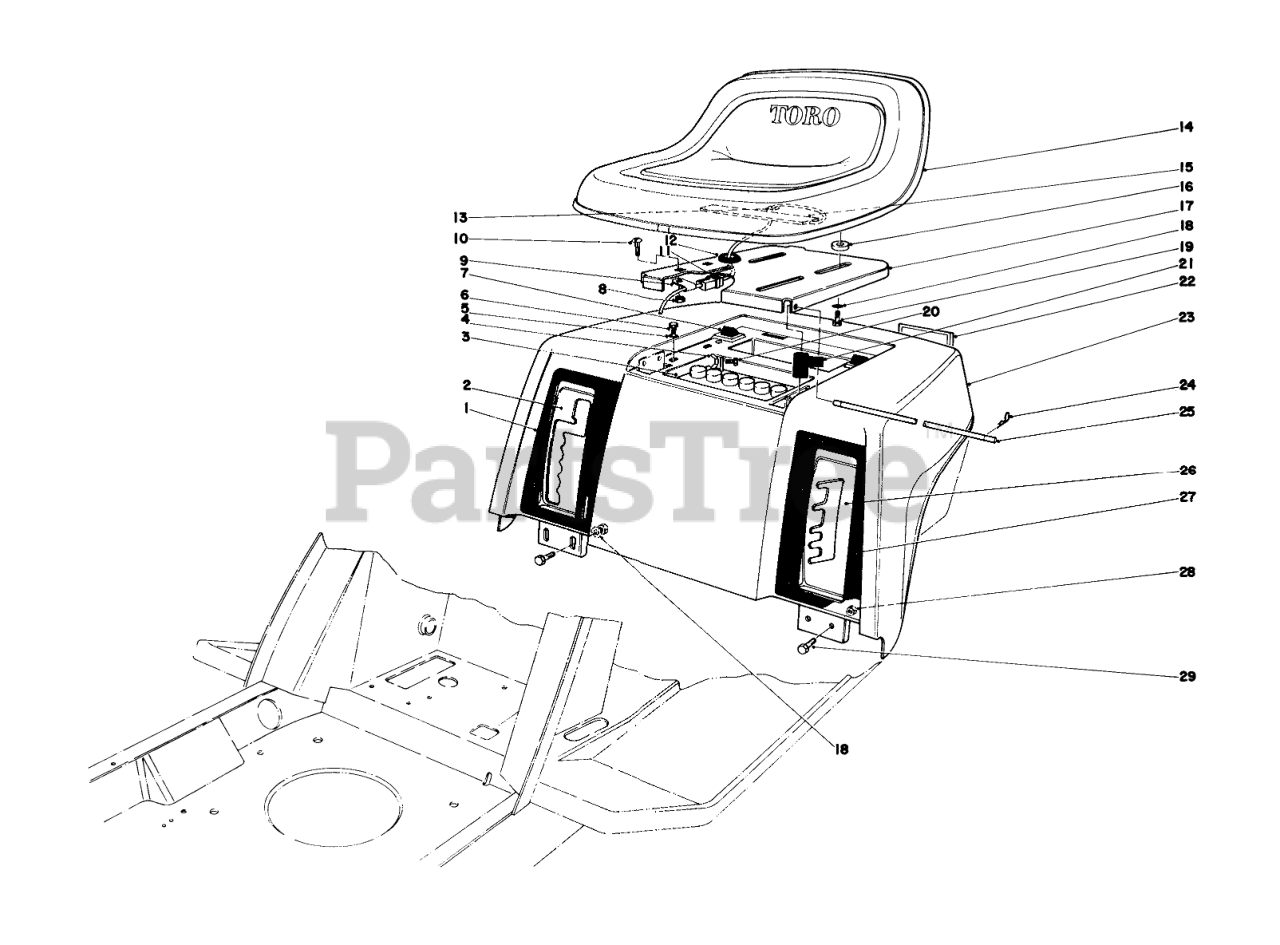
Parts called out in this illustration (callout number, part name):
1	Decal-Transmission
2	DETENT PLATE B
3	Battery
4	NUT-WING
5	WASHER
6	SCREW-HWHTF
7	SEAT BUMPER
8	NUT-LOCK, CONE
9	CLAMP
10	SCREW-CARR
11	Connector-Female
12	GROMMET
13	Clip
14	Seat (Incl. Ref. #11, 13 & 15) (Model #57360)
15	Switch-Seat
16	SPACER-PIN, MOUNTING
17	SEAT SUPPORT R
18	WASHER-PLAIN
19	SCREW-HH
20	SCREW-HH
21	BOOT-TERMINAL
22	REFLECTOR
23	Rear Body
24	PIN-COTTER
25	PIVOT-SEAT
26	Quadrant Height of Cut
27	Decal Height of Cut
28	NUT-LOCK, CONE
29	SCREW-HH
